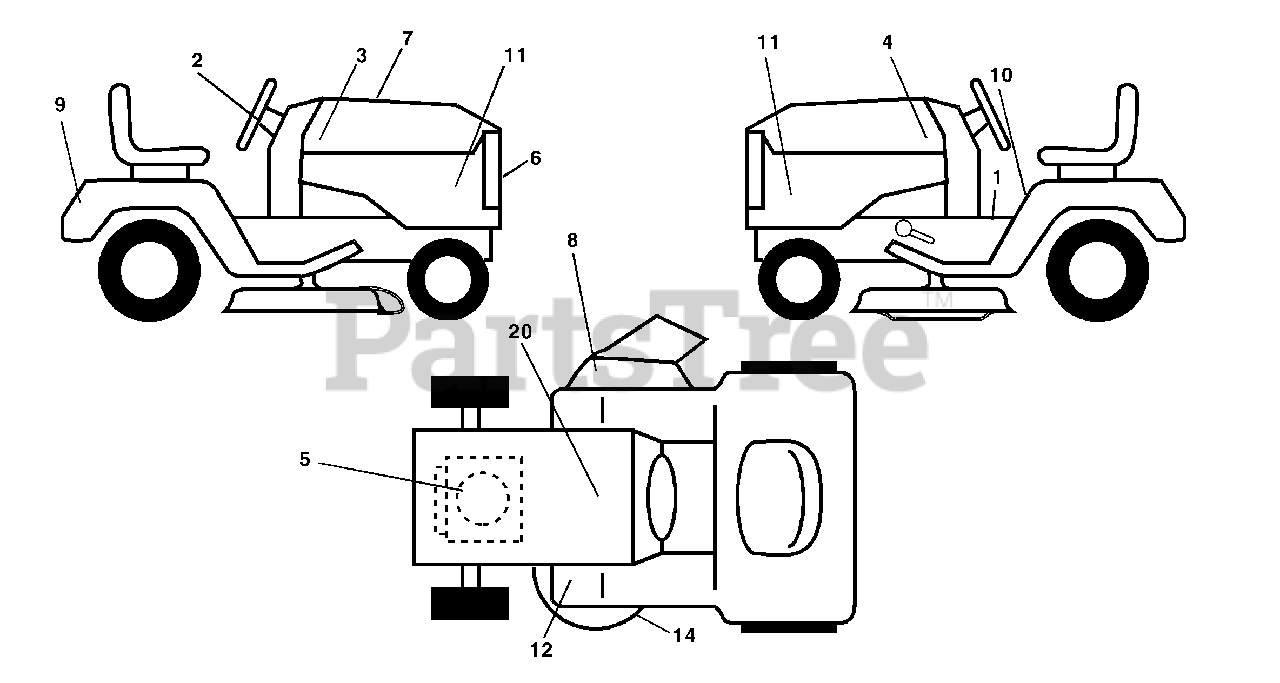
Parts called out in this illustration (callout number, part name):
1	Decal Oper Inst Hyd E/F
2	Decal Strg Wheel Logo
3	Decal Hood RH
4	Decal Hood LH
5	Decal Engine
6	Decal Grille Husq
7	Decal Final
8	Decal Warning
9	Decal Fender Husq
10	Decal Fender Danger E/F
11	Decal Hood Sides
12	Decal Clutch/Brake
14	Decal V-Belt Schematic
20	Decal Bat Dan/Psn
